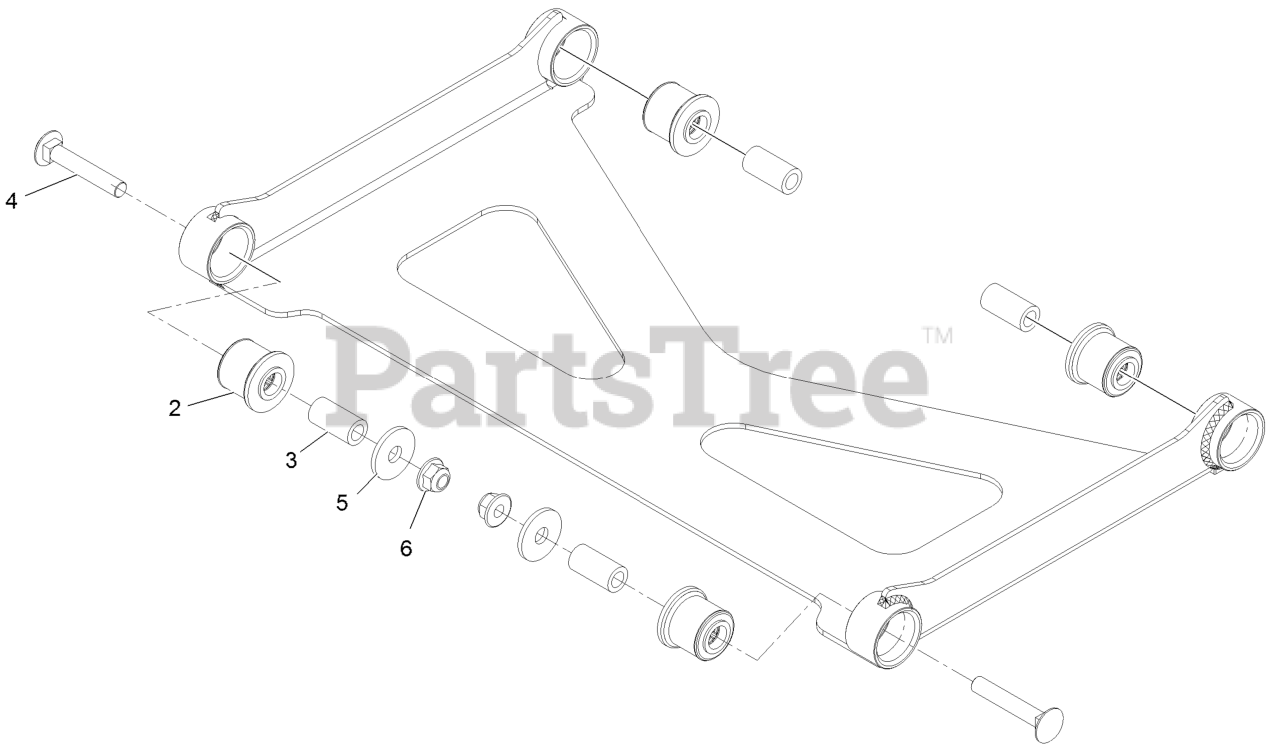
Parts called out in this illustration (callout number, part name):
2	BUSHING-RUBBER, SUSPENSION
4	Bolt-Carriage 3/8-16 X 2 1/4
5	WASHER
6	NUT-HF, NI
